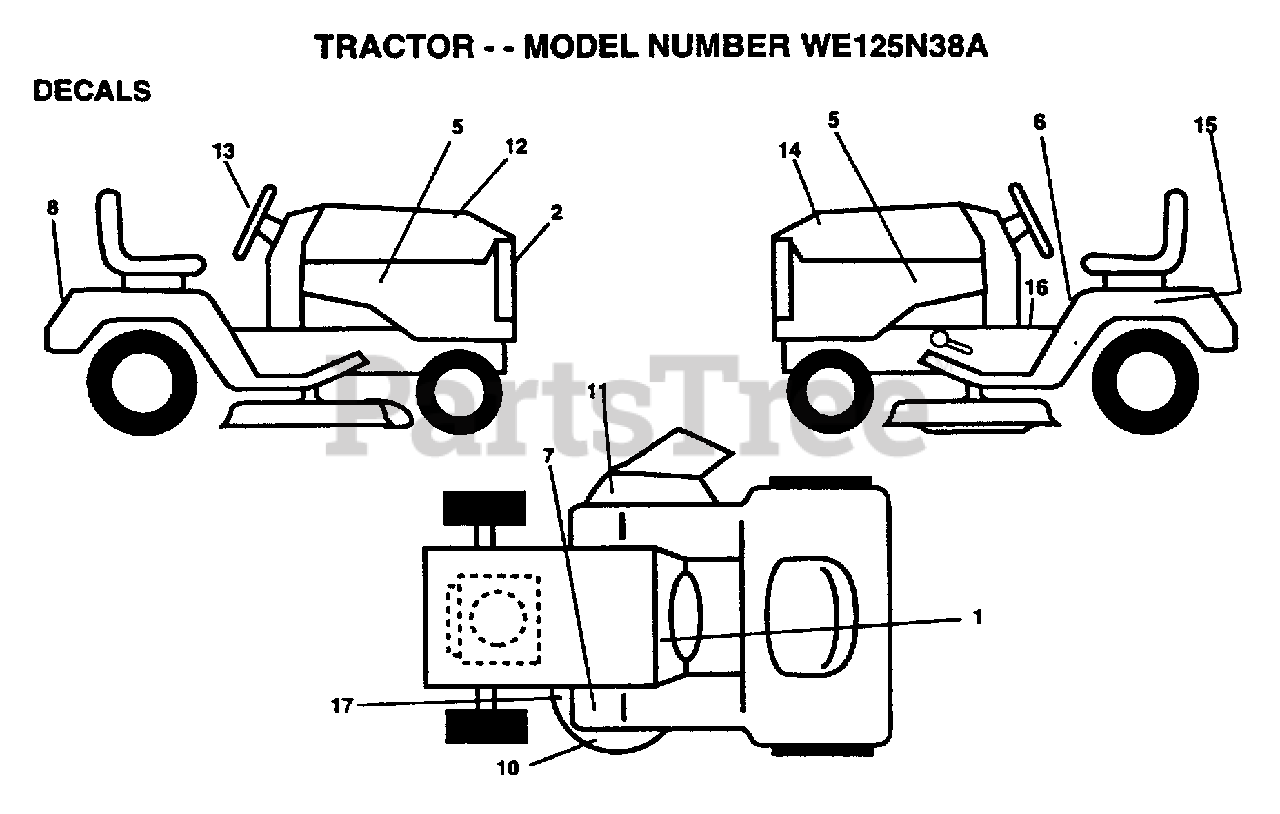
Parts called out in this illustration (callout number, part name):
1	DECAL.DASH.INSTR.
2	DECAL.GRILL
5	DECAL.PNL.SD.12.5
6	DECAL CAUTION
7	DECAL T
8	DECAL.FENDER
10	DECAL.MOWER
11	"DECAL, WARNING"
12	DECAL.HD.RH.WEED.
13	DECAL.WHL.STRG.
14	DECAL.HD.LH.WEED.
15	DECAL
16	DECAL BRAK PARK
17	DECAL
